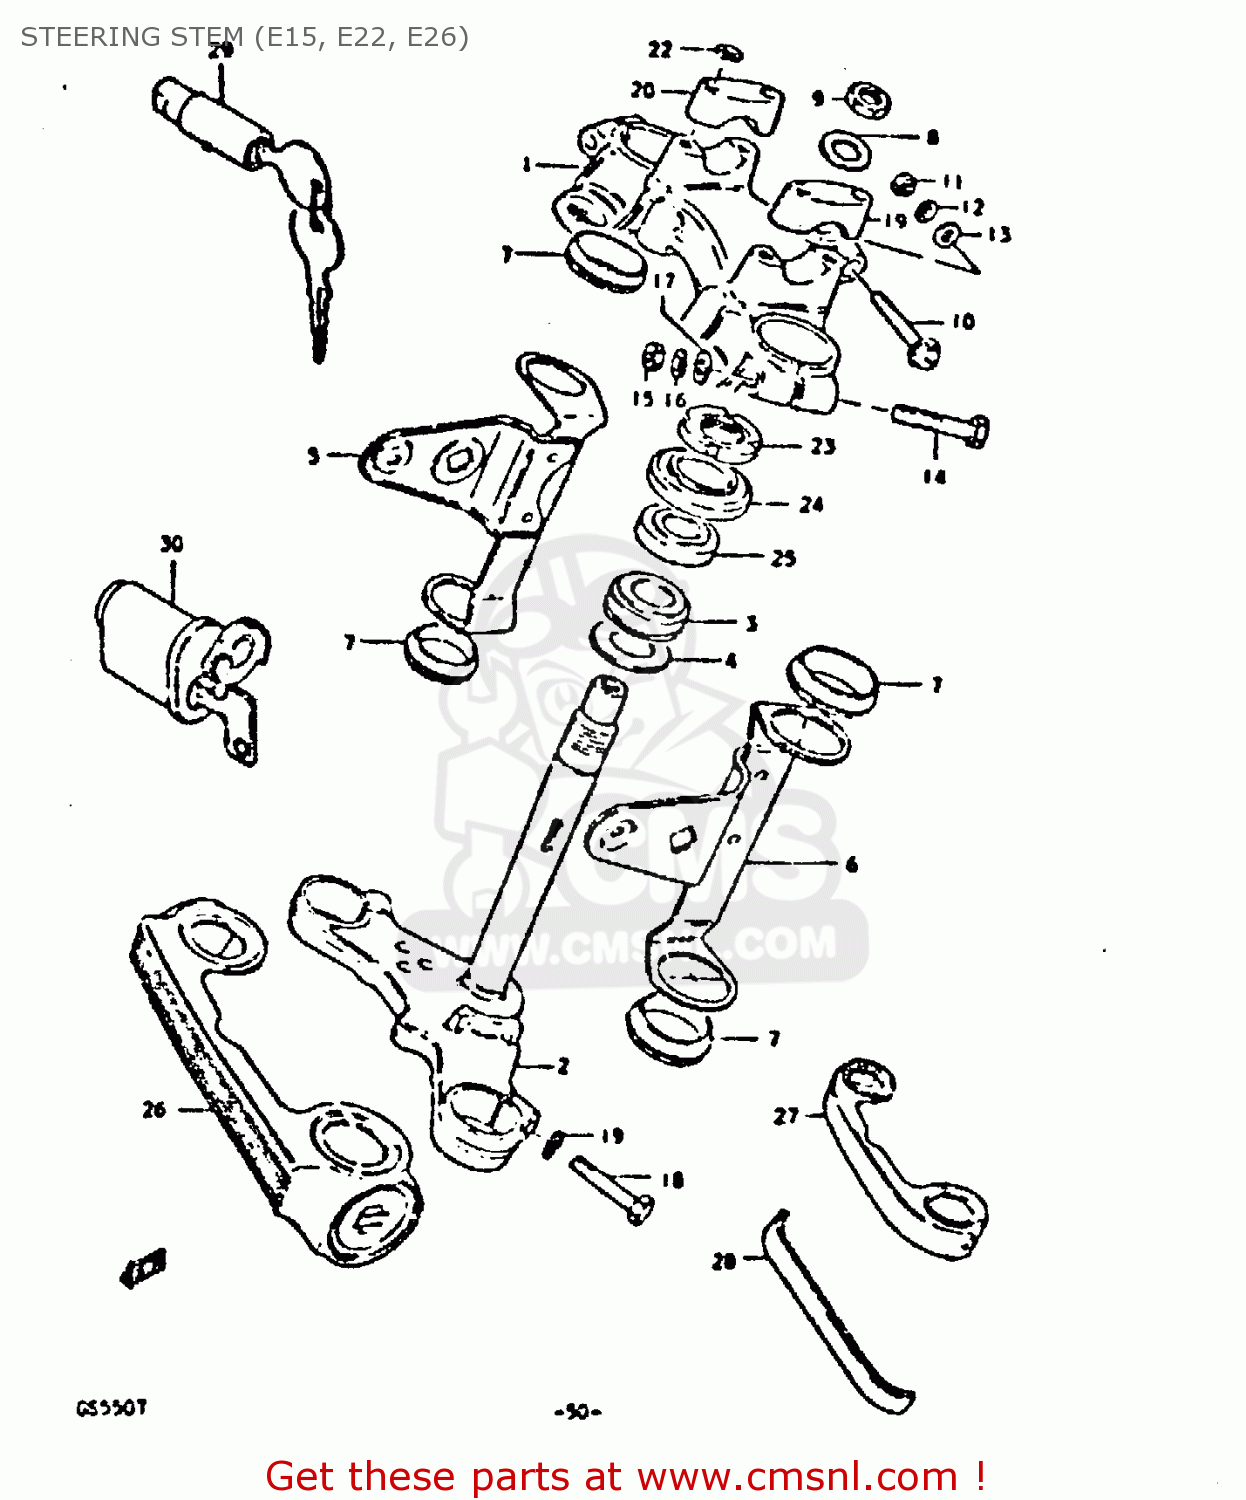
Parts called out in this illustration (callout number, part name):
1	HEAD,STEERING STEM
2	STEM,STEERING
3	BEARING
4	WASHER,THRUST
5	BRACKET,HEADLAMP,RIGHT
6	BRACKET,HEADLAMP,LEFT
7	CUSHION,HEADLAMP BRACKET
8	WASHER
9	NUT,FR FORK UPR BRACKET
10	BOLT
11	NUT
12	LOCK WASHER
13	WASHER
14	BOLT 10X55
15	NUT
16	LOCK WASHER
17	WASHER
18	BOLT 10X40
19	LOCK WASHER
20	HOLDER,HANDLE UPR
21	BOLT
22	LOCK WASHER
23	NUT,STEERING STEM(25X44X10)
24	DUST SEAL,STEERING,UPPER
25	TAPER,ROLLER BEARING
26	COVER, FRONT FORK
27	COVER,FRONT FORK
28	PROTECTOR, FRONT FORK COVER
29	LOCK ASSEMBLY,STEERING (NEI
30	LOCK ASSY, STEERING (NEIMAN TYPE EXECUTE
